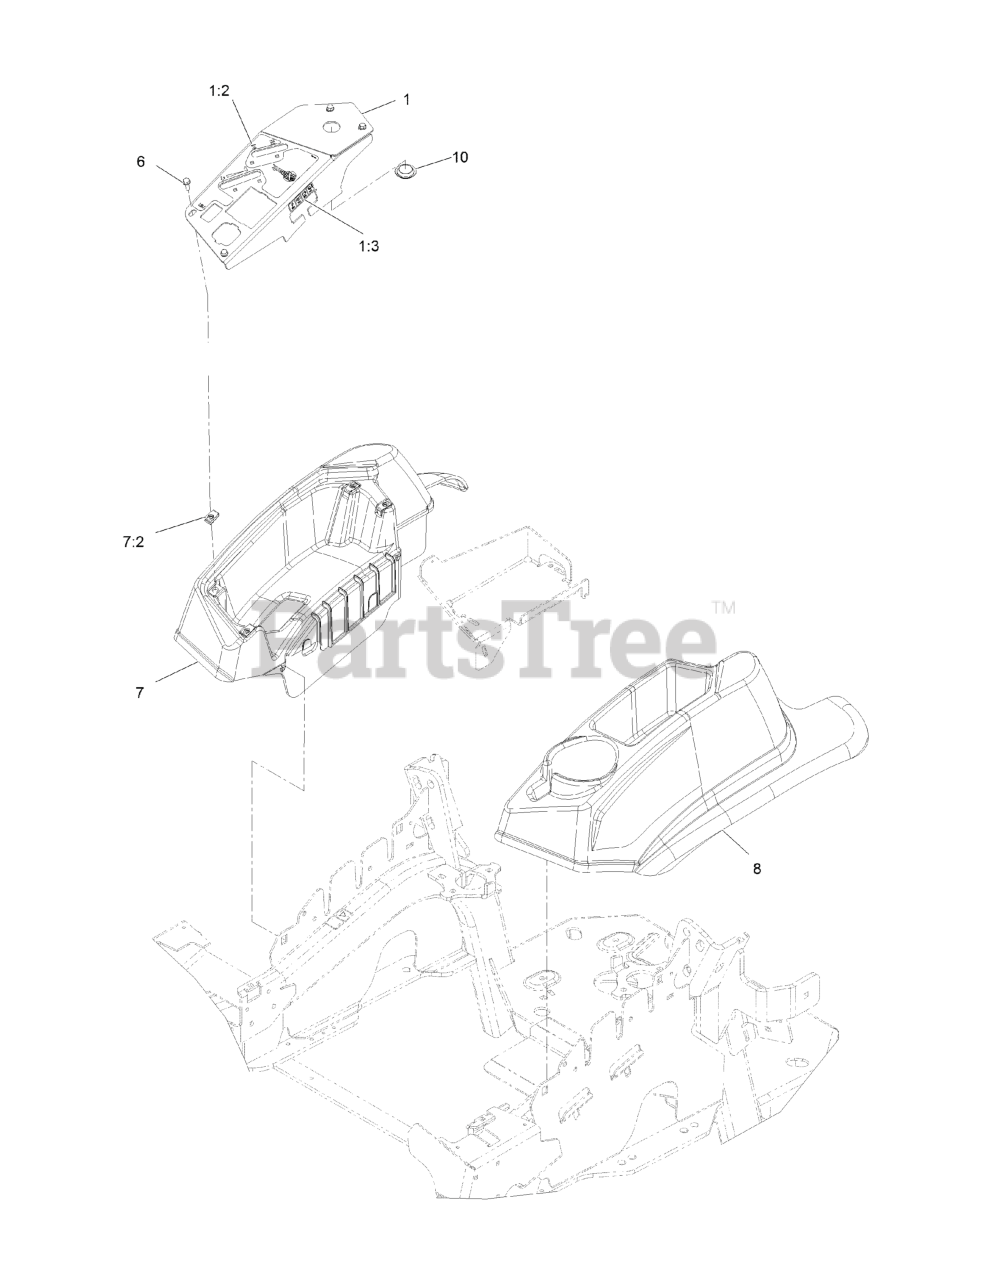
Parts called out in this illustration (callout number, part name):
1	CONSOLE,PANEL W/DECAL
1:2	DECAL-CONTROL PANEL NON-EFI
1:3	DECAL-FUSES
6	SCREW-HWH
7	CONSOLE,RH AS ASM
8	CONSOLE, LH AS
10	PLUG-PLASTIC
